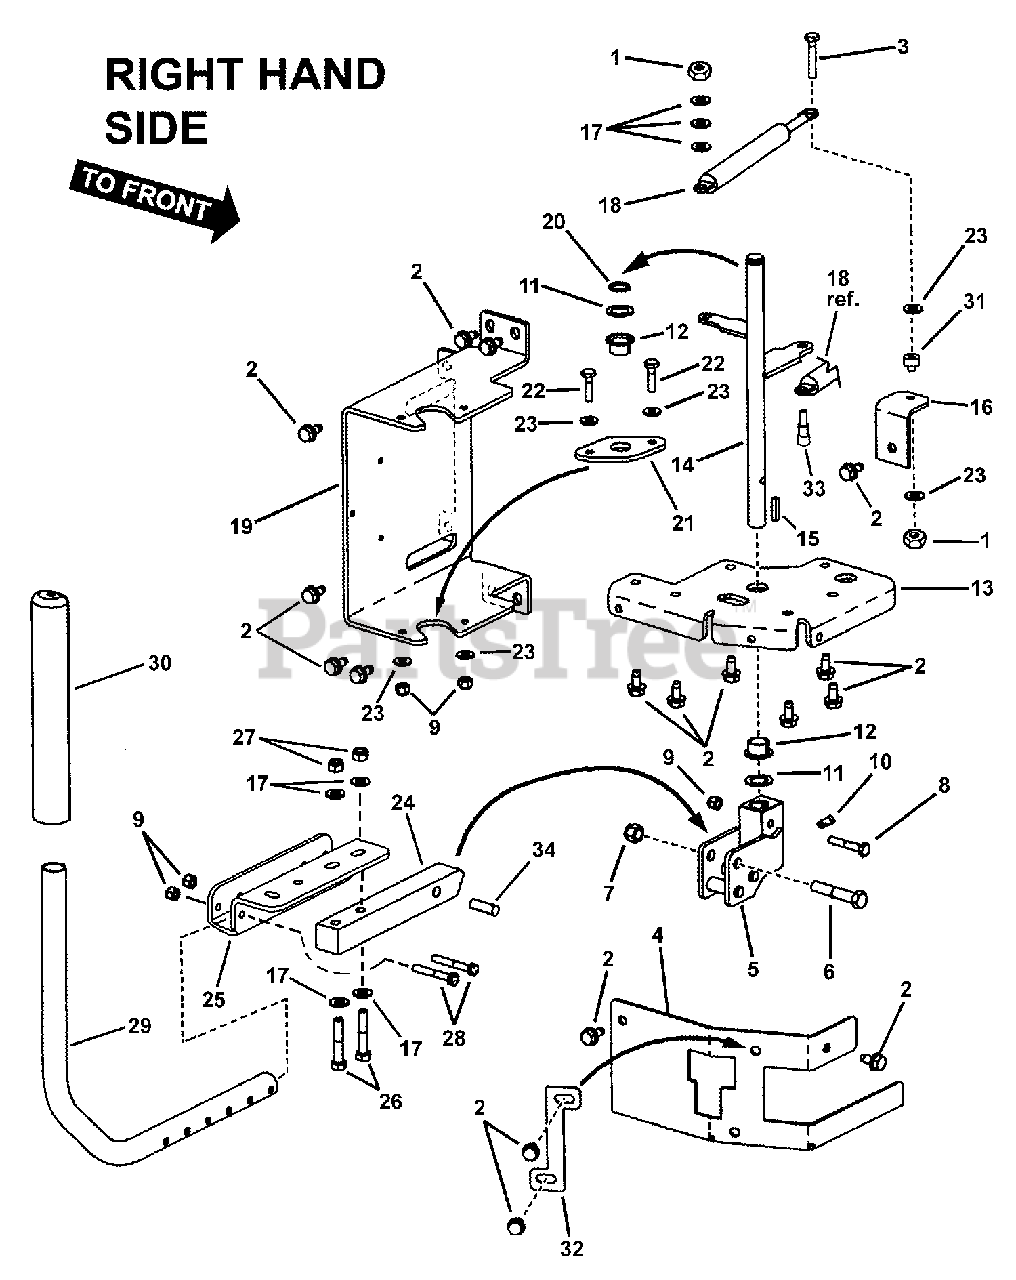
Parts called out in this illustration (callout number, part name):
1	NUT, 1/4-20 Hex Center Lock
2	SCREW, 5/16-18 x 5/8" Hex Washer Self-Tap
3	SCREW, 1/4-20 x 1-1/4" Hex Head Cap
4	LIMITER BRACKET, Right Hand
5	WELDMENT, Mounting Hub
6	BOLT, 3/8-16 X 2, GD5, CZ
7	NUT, 3/8-16 HEX NYLON LOCK
8	SCREW, 1/4-20 x 1-1/2" Hex Head Cap GR 5
9	NUT, 1/4-20 HEX NYLON LOCK
10	SET SCREW, 5/16-18 Square Head w/Patch
11	WASHER, .64 I.D. x .99 O.D. x .05 Flat
12	BUSHING, Teflon Impregnated
13	BUSHING MOUNT PLATE, Right Hand
14	WELDMENT, Cross Rod, RH
15	KEY, 3/16" Square x 7/8" Long
16	BRACKET, Dampener Frame
17	WASHER, 5/16" Flat
18	CYLINDER, Dampener
19	CHANNEL, Mounting
20	RING, 5/8" External Retaining
21	MOUNTING PLATE, Left Hand Bearing
22	BOLT, 1/4-20 X 1" GD5 CZ
23	WASHER, .28 I.D. x .63 O.D. x .06 Thick Flat
24	MOUNTING ARM
25	BRACKET, Handle Adjustment
26	BOLT, 5/16-18 X 1-3/4 GD5 YZ
27	NUT, 5/16-18 HEX NYLON LOCK
28	BOLT, 1/4-20 X 1-3/4" GD5 YZ
29	HANDLEBAR
30	GRIP, Twin Stick
31	SPACER
32	BRACKET, Speed Control
33	SCREW, 1/4-20 Shoulder Socket Head
34	SPACER, .498 O.D. x 1.010" long
